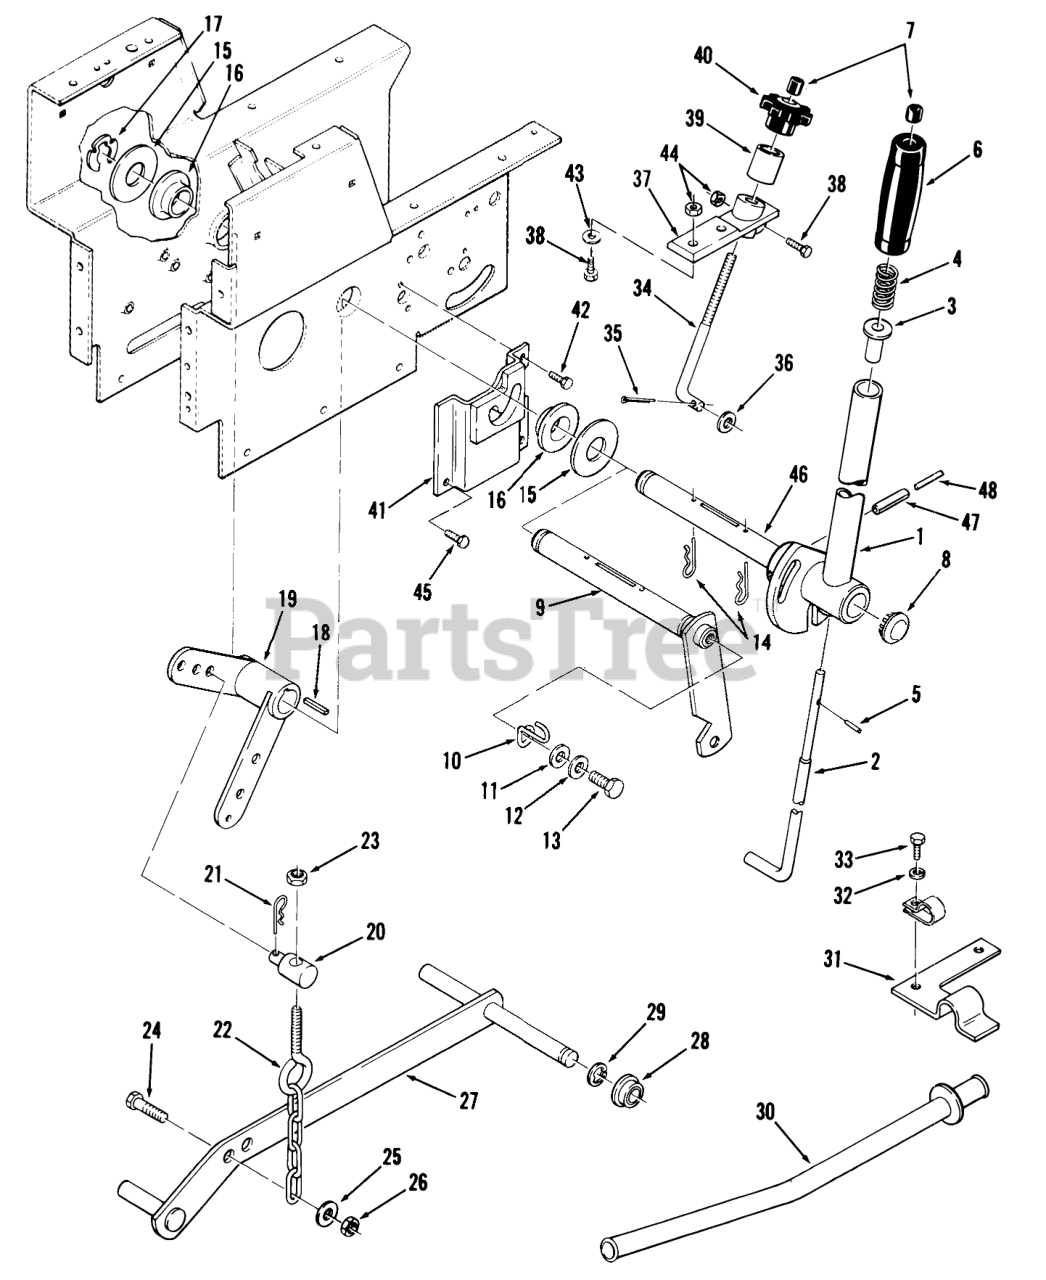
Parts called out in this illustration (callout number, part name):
26	Nut
27	ASSY LIFT BAR R
28	BUSHING
29	E Ring
30	TUBE ASSY COMPLET R
31	Clamp-Tube
32	LOCKWASHER
33	Bolt
34	Rod
35	Pop Rivet
36	WASHER -4
37	Casting
38	Bolt
39	Sleeve
40	KNOB-LIFT CONTROL
41	Latch Bracket
42	SCREW
43	WASHER 5/16 SAE
44	Nut
45	Bolt
46	SHAFT-LIFT LEVER
47	SPIROL PIN
48	Roll Pin
